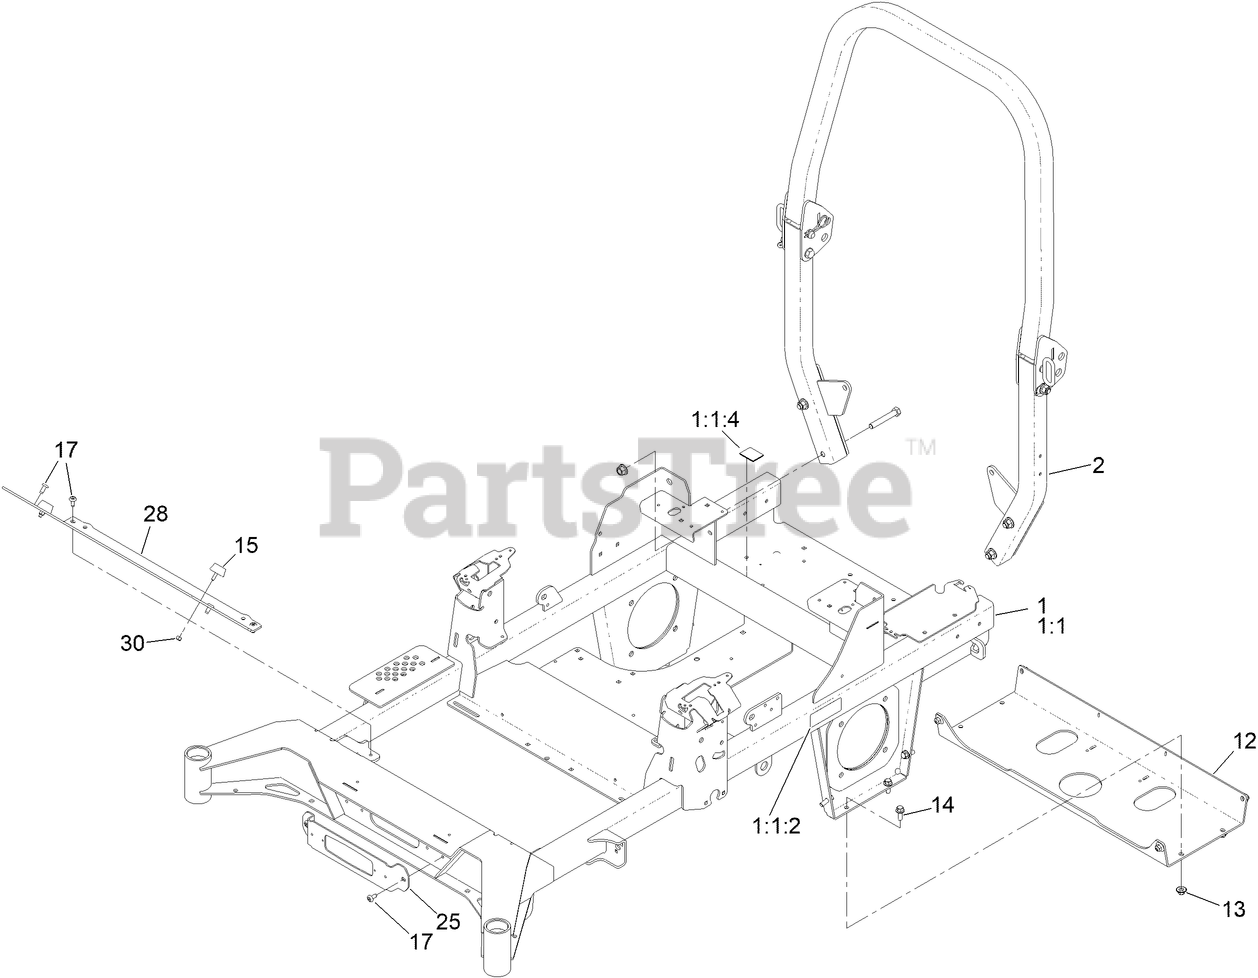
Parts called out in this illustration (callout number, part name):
1	FRAME DECAL ASM
1:1:2	DECAL-WARNING
1:1:4	DECAL, BELT ROUTING
2	ASM-ROPS
12	PLATE-HYDRO
13	NUT-FLANGE, NI
14	SCREW-HHF
15	BUMPER
25	BRACKET-LIGHT
28	TOEBOARD [RED]
30	NUT-LOCK, NI
